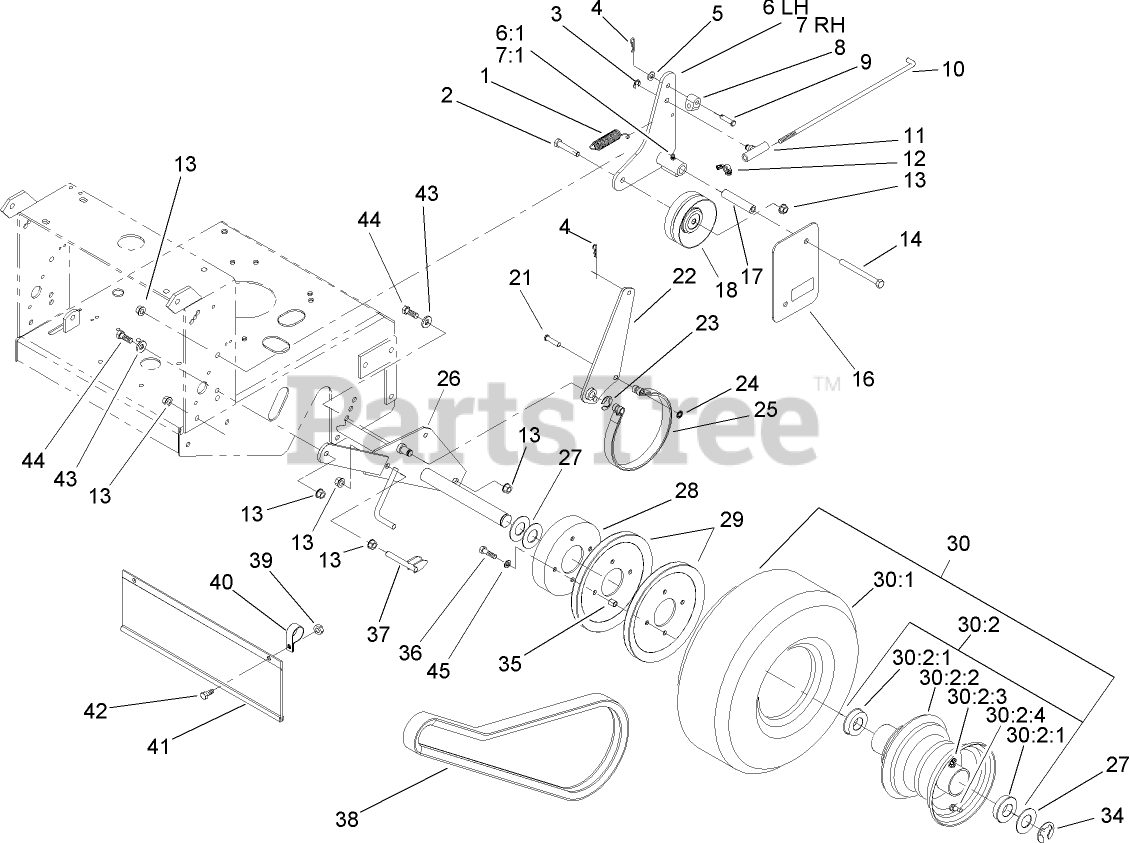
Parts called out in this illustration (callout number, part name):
1	SPRING-EXTENSION
2	SCREW-HH
3	RING-RETAINING
4	PIN-COTTER
5	WASHER-PLAIN
6	RH IDLER ARM ASM
6:1	FITTING-GREASE
7	LH IDLER ARM ASM
7:1	FITTING-GREASE
8	FITTING-ROD
9	PIN-CLEVIS
10	ROD-BRAKE
11	SWIVEL-BRAKE
12	WINGNUT-NYLOCK
13	NUT-HHF, WHIZ
14	SCREW-HH
16	SHIELD-WHEEL, DRIVE
17	SPACER-SHIELD
18	IDLER-DRIVE, WHEEL
21	PIN-CLEVIS
22	ARM-BRAKE
23	RING-RETAINING, EXTERNAL
24	NUT-PUSH
25	BAND-BRAKE
27	WASHER-SPACER
28	DRUM-BRAKE
29	SHEAVE-WHEEL, DRIVE
30	WHEEL AND TIRE ASM
30:1	Tire-Turfmaster
30:2	WHEEL AND HUB ASM
30:2:1	BEARING-FLANGED
30:2:2	Rim ASM
30:2:3	Fitting-Grease
30:2:4	Stem-Valve
34	RING-SNAP
35	SPACER-SHEAVE, WHEEL
36	SCREW-HH
37	SCRAPER
38	V-BELT
39	NUT-LOCK, NI
40	CLAMP-R
41	SHIELD-TRAILING
42	SCREW-HH
43	WASHER-BELLEVILLE
44	SCREW-HH
45	WASHER
